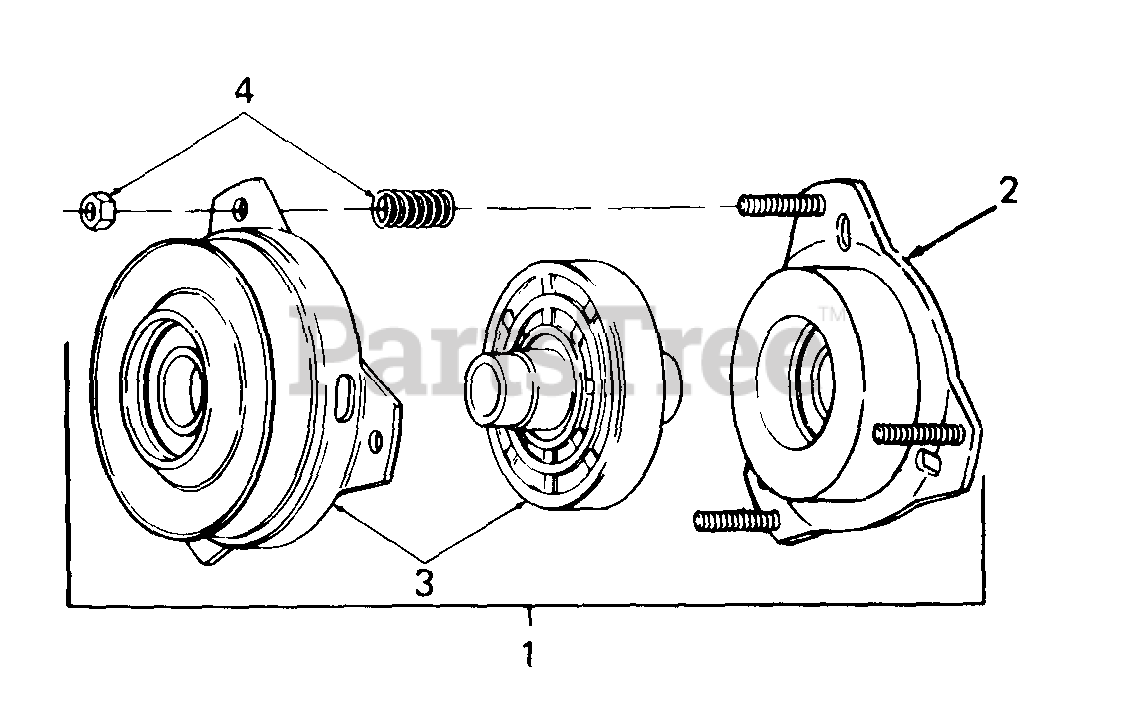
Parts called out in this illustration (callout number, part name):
1	Clutch Assy, PTO
2	Field Assy
3	Kit, Rotor & Armature
4	Mounting Accessories
